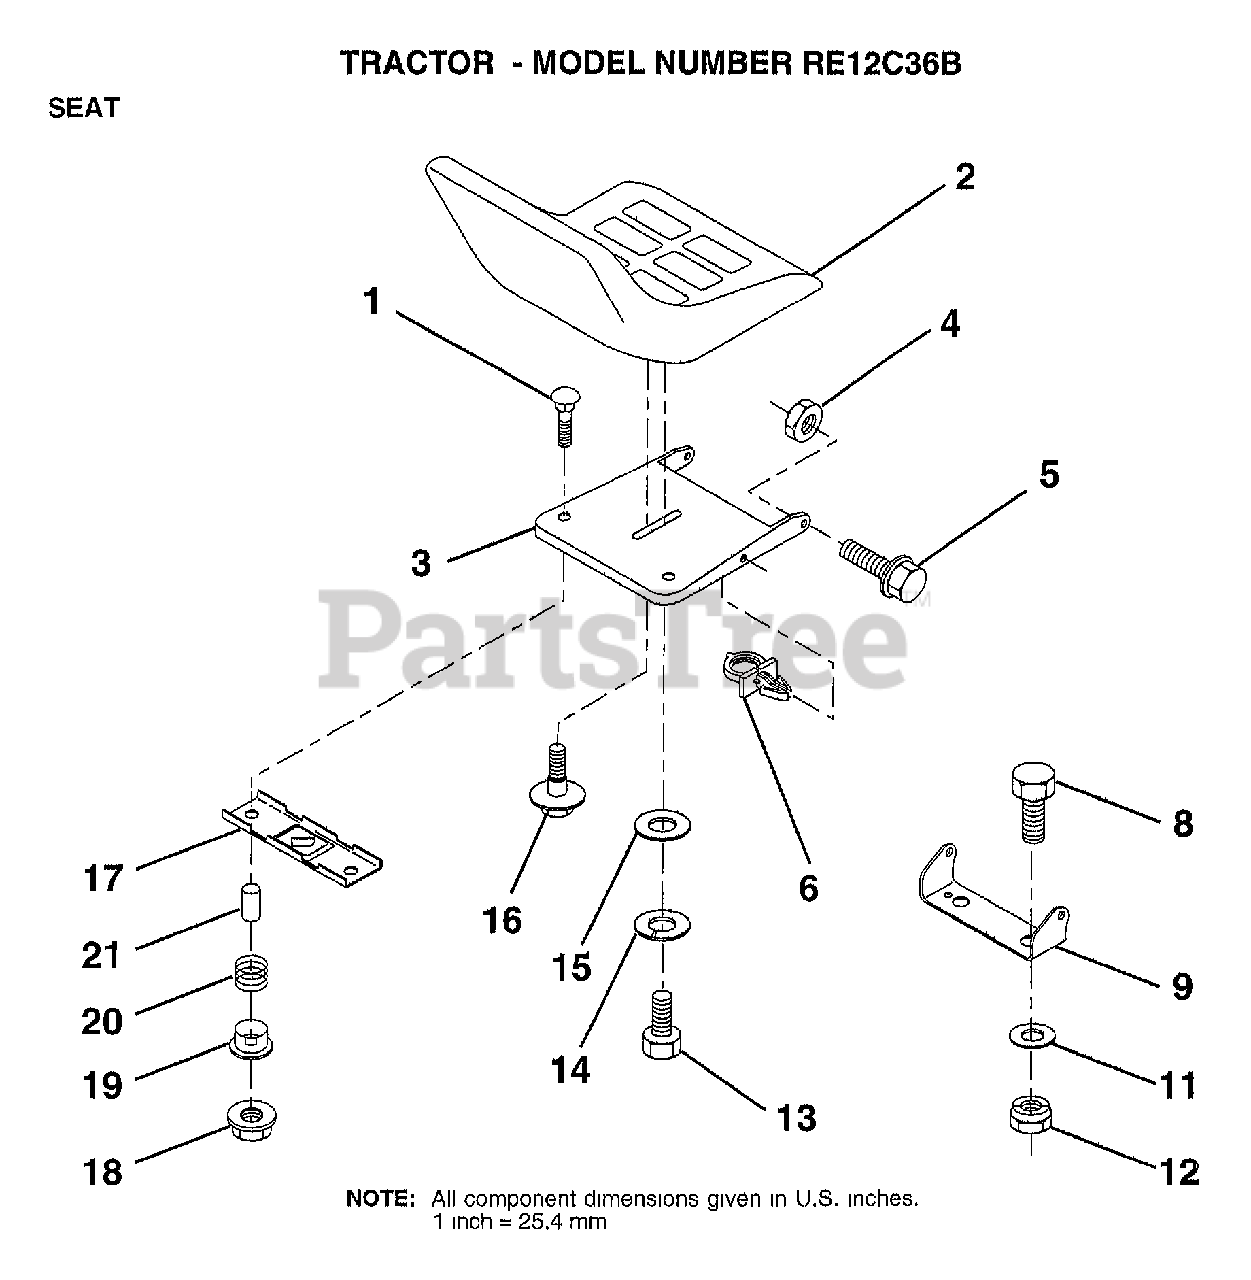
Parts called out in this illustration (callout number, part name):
1	BOLT-RD HD SQ NK
3	PAN-SEAT
4	NUT
5	"BOLT,SHOULDER"
6	CLIP.PUSH-IN.HING
8	BOLT
9	BRACKET PVT SEAT
11	WASHER
12	NUT
13	BOLT
14	LOCKWASHER
15	WASHER
16	"BOLT,SHOULDER"
17	BRKT SWITCH
19	BUSHING
20	SPRING
21	SPLIT SPACER
